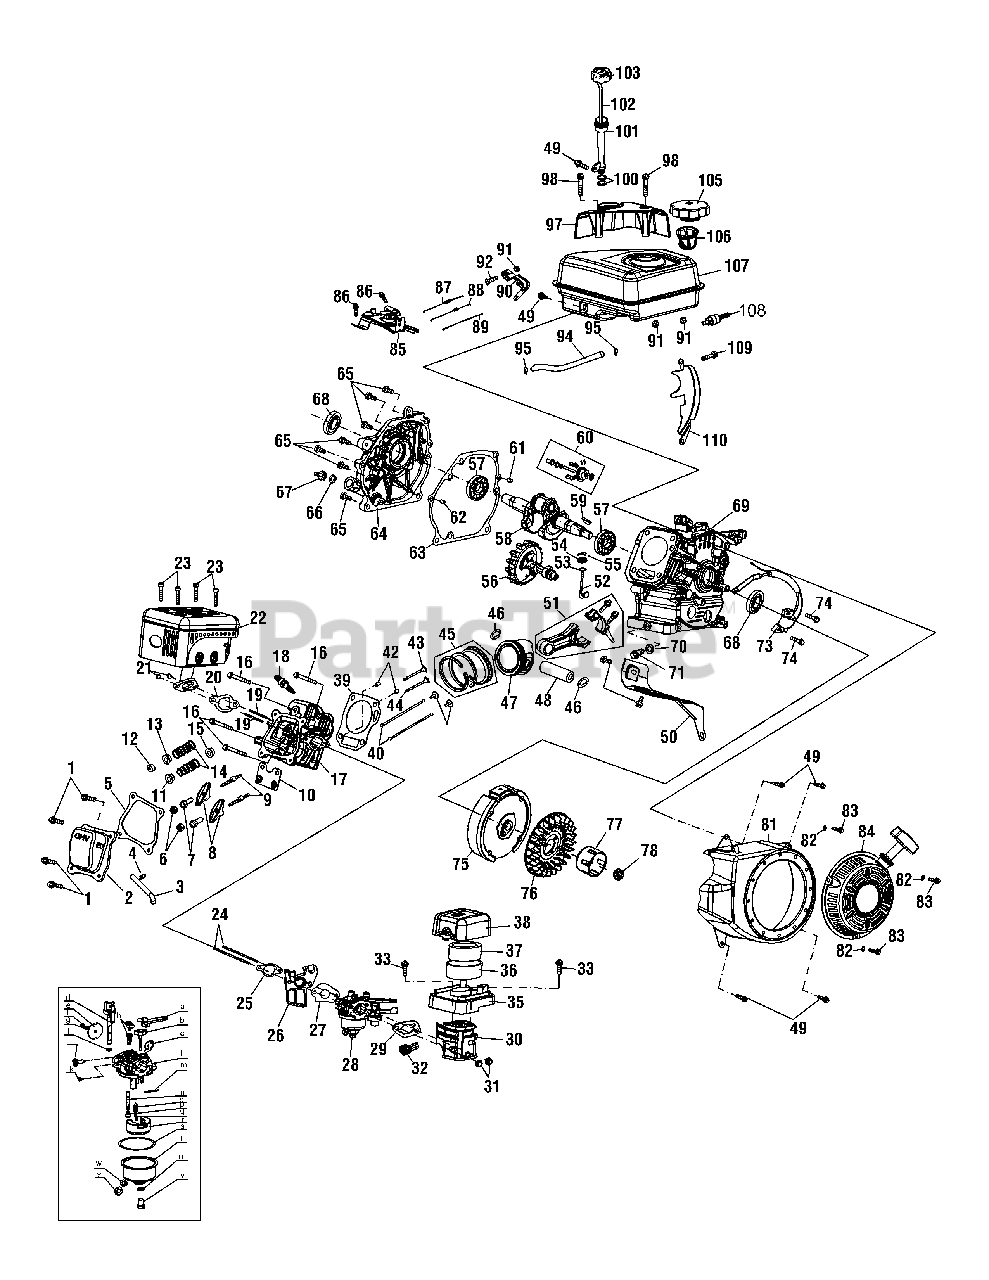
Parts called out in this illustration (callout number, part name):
1	Bolt
2	Valve Cover
3	Breather Hose
4	Breather Hose Clamp
5	Valve Cover Gasket
6	Nut, Pivot Locking
7	Valve Adjusting Nut
8	Rocker Arm
9	Rocker Arm Stud
10	Push Rod Guide
11	Valve Spring Retainer-Intake
12	Exhaust Valve Adjustor
13	Valve Spring Retainer-Exhaust
14	Valve Spring
15	Valve Seal
16	Cylinder Head Bolt
17	Cylinder Head
18	Spark Plug
19	Muffler Stud
20	Exhaust Pipe Gasket
22	Muffler Assembly
23	Bolt
24	Carburetor Stud
25	Carburetor Insulator Gasket
26	Carburetor Insulator
27	Carburetor Gasket
28	Carburetor Assembly
29	Carburetor Gasket Plate
30	Air Cleaner Housing
32	Throttle Control Knob
33	Self-Tapping Bolt
35	Lower Housing
36	Air Cleaner Foam Wrap
37	Air Cleaner Element
38	Upper Housing
39	Cylinder Head Gasket
40	Push Rod Kit
41	Valve Lifter
42	Dowel Pin
43	Exhaust Valve
44	Intake Valve
45	Piston Ring Set
46	Piston Pin Clip
47	Piston
48	Piston Pin
50	Air Shield
51	Connecting Rod Assembly
52	Governor Arm Shaft
53	Governor Shaft O-Ring
54	Governor Seal
55	Cotter Pin
56	Camshaft Assembly
57	Radial Ball Bearing
58	Crankshaft Assembly
59	Flywheel Key
60	Governor Assembly
61	Dowel Pin, 7 x 14
62	Dowel Pin, 9 x 14
63	Crankcase Cover Gasket
64	Crankcase Cover
65	Bolt
66	O-Ring
67	Oil Filler Plug
68	Oil Seal
69	Crankcase Complete
70	Oil Drain Plug Washer
71	Oil Drain Plug
73	Ignition Coil
76	Cooling Fan
77	Starter Cup
78	Nut
81	Blower Housing
82	Washer
84	Recoil Starter Assembly
85	Primer Bracket
87	Governor Spring
88	Throttle Linkage Spring
89	Throttle Linkage
90	Governor Arm
91	Nut
92	Governor Arm Bolt
94	Fuel Hose
95	Hose Clamp
97	Engine/Dipstick Cover
101	Dipstick Tube
102	Dipstick Gauge
103	Dipstick Cap
105	Fuel Cap
106	Fuel Filter
107	Fuel Tank
108	Fuel Tank Nipple
110	Blower Housing Shield
